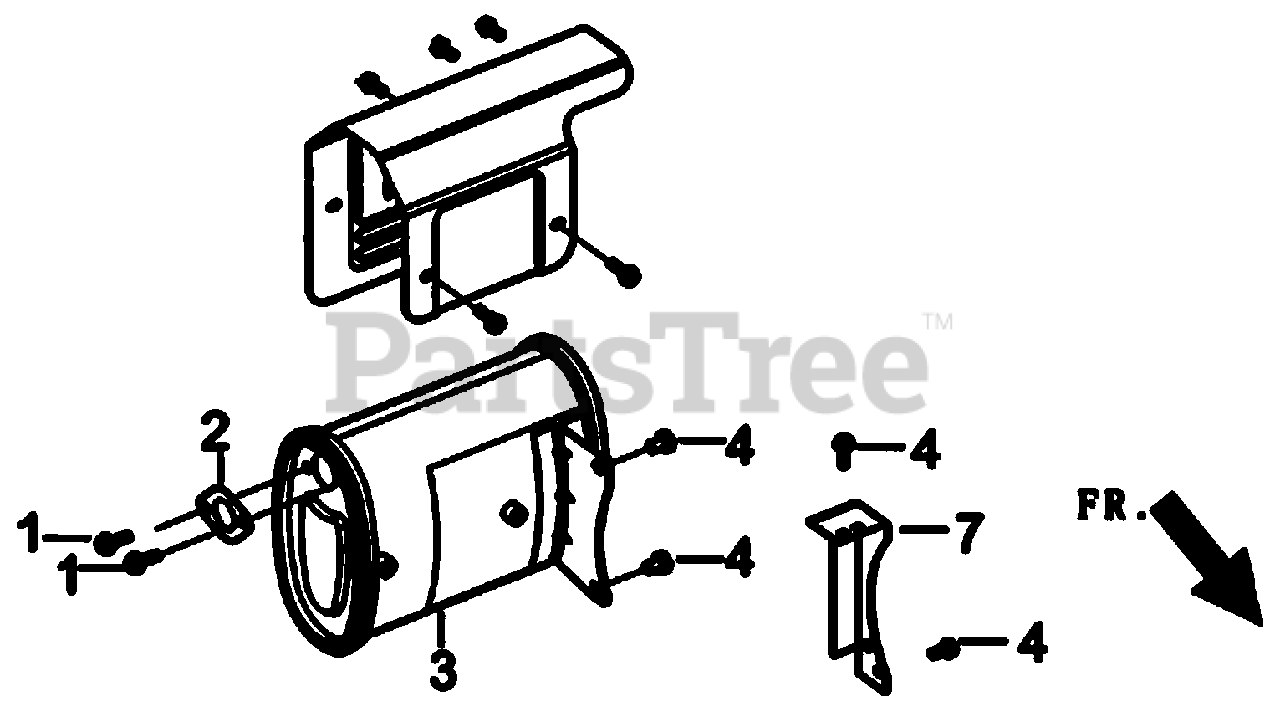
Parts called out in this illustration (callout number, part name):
1	BOLT
2	GASKET, EXHAUST OUTLET
3	MUFFLER ASSY.
4	BOLT
7	BRACKET, MUFFLER
